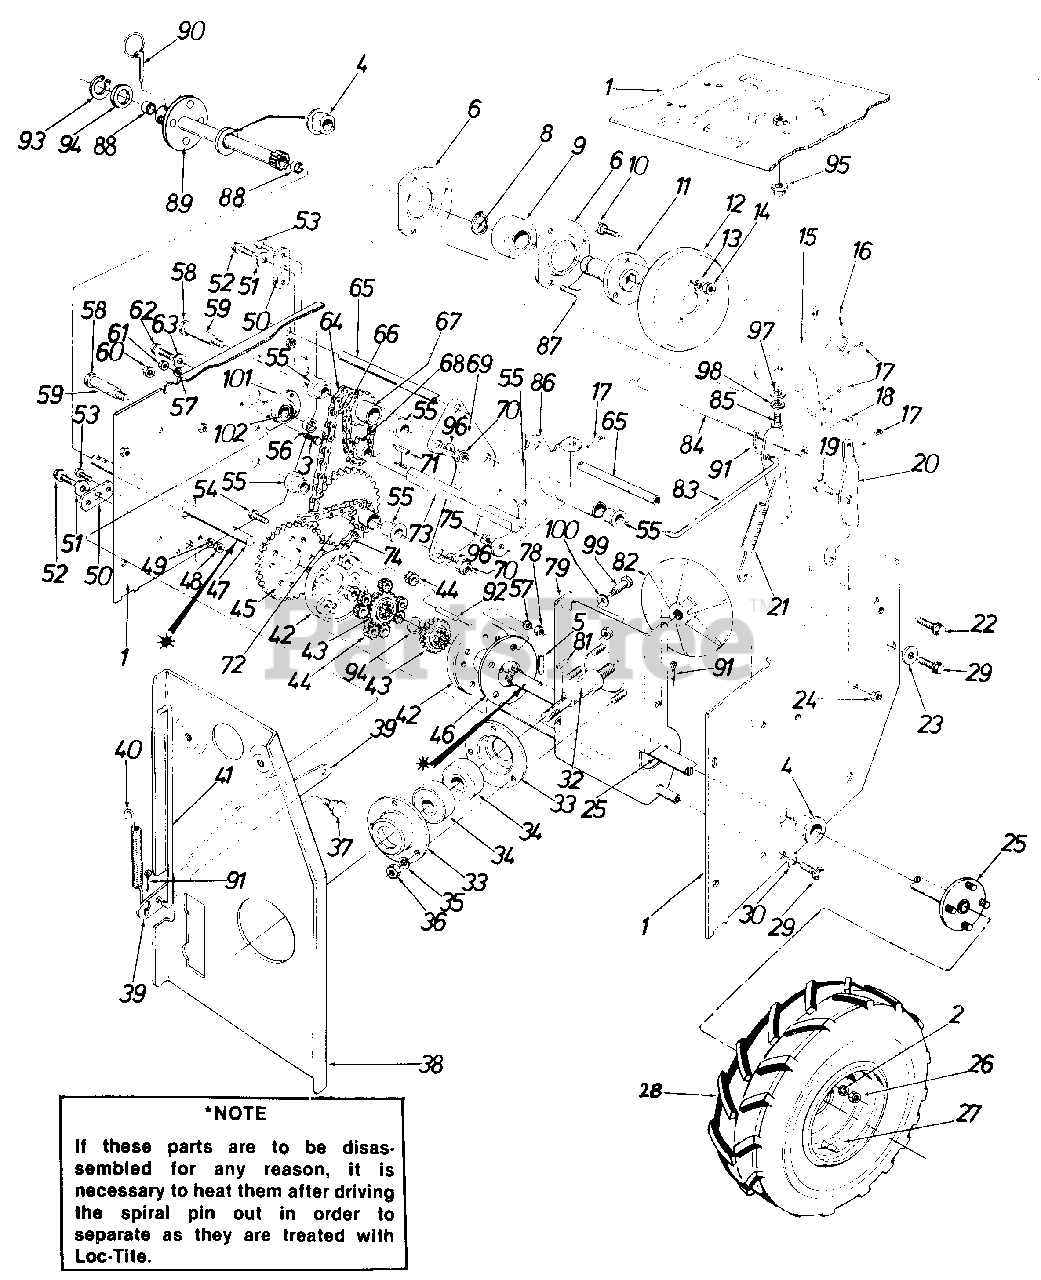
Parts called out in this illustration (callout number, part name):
1	Frame Ass'y.
2	L-Wash. 3/8" Scr.
3	Hex Bolt 1/4-20 x .62" Lg.
4	Flange Brg. w/Flats 1.00" I.D.
5	H-Spring Pin Spiral 3/16" Dia. x 1.25" Lg.
6	Bearing Housing
8	Snap Ring for 1.00" Dia. Shaft
9	Ball Brg. 25 mm x 52 mm x 15 mm Thk.
10	Hex Sems Scr. 5/16-18 x .75" Lg.
11	Friction Wheel Adapter
12	Friction Wheel Ass'y.
13	L-Wash. 5/16" Scr.
14	Hex Nut 5/16-18" Thd.
15	Sliding Linkage Brkt.
16	Brake Rod - .31" Dia. x 2.00" Lg.
17	Cot. Pin 3/32" Dia. x .75" Lg.
18	Shifting Linkage Rod .31" Dia. x 2.25" Lg.
19	Shld. Scr. .625" Dia. x .170" Lg.
20	Shifting Linkage Brkt.
21	Extension Spring .73 O.D. x 4.31" Lg.
22	Hex L-Scr. 5/16-18 x .62" Lg.
23	Fl-Wash. .345 I.D. x .75 O.D. x .060
24	Hex Cent. L-Nut 3/8-16 Thd.
25	Differential Shaft Ass'y. - L.H.
26	Hex Nut 3/8-16 Thd.
27	Wheel Rim Ass'y.
28	Wheel Ass'y. Comp. 16.0 x 4.80-8
29	Hex L-Scr. 5/16-18 x .62" Lg.
30	Fl-Wash. .345" I.D. x .75 O.D. x .060
32	Drive Plate Spindle
33	Bearing Housing
34	Ball Brg. .787 I.D. x 1.85 O.D. x .56
35	L-Wash. 5/16" Scr.
36	Hex Nut 5/16-18 Thd.
37	Shld. Scr. .625" Dia. x .170" Lg.
38	Engine Brkt. Ass'y.
39	Auger Clutch Brkt.
40	Extension Spring .38 O.D. x 3.18" Lg.
41	Auger Clutch Rod .31" Dia. x 10.62" Lg.
42	Differential Housing
43	20 Tooth Spur Gear
44	9 Tooth Spur Gear
45	28 Tooth Sprocket
46	Differential Hsg. Support Plate
47	Differential Connecting Shaft
48	Hex Nut 1/4-20 Thd.
49	L-Wash. 1/4" Scr.
50	Pivot Axle Brkt.
51	Fl-Wash. .345" I.D. x .88" O.D. x .060
52	Hex L-Scr. 5/16-18 x .62" Lg.
53	Hex Scr. 1/4-20 x .62" Lg.
54	Hex Scr. 1/4-28 x 1.75" Lg.
55	Flange Brg. - .630" I.D.
56	Spacer .51" I.D. x .69" O.D. x .44
57	L-Wash. 1/4" Scr.
58	Hex Scr. 3/8-24 x 2.75" Lg.
59	Sprocket Hub Tubing 1.900" Lg.
60	Hex Cent. L-Nut 3/8-16 Thd.
61	Hex Nut 1/4-20 Thd.
62	Hex L-Scr. 5/16-18 x .62" Lg.
63	Bell-Wash. .345" I.D. x .88 O.D. x .060
64	#41 Chain - 1/2" Pitch x 43 Links
65	Sliding Support Axle
66	#41 Chain 1/2" Pitch x 19 Links
67	9 and 14 Teeth Sprocket Hub Ass'y.
68	8 Teeth Sprocket
71	#9 Hi-Pro Key 3/32 x 5/8" Dia.
72	9 and 32 Teeth Sprocket Hub Ass'y.
73	Hex Shaft
74	#420 Chain - 1/2" Pitch x 37 Links
75	Hex Ins. Jam L-Nut 1/4-28"
78	Hex Nut 1/4-28 Thd.
82	Aluminum Drive Plate
83	Drive Clutch Rod .31" Dia. x 7.38" Lg.
84	Drive Clutch Brkt. Ass'y.
85	Hex Scr. 3/8-16 x 1.00" Lg.
86	Sliding Brkt. Ass'y.
87	Hex Scr. 1/4-28 x .62" Lg.
88	Sleeve Brg. .630 I.D.
89	Differential Tubing Ass'y. - R.H.
90	Klick Pin 1/4" Dia. x 1.75" Lg.
91	Internal Cot. Pin 5/16 Dia.
92	Differential Pin
93	Snap Ring .625 Shaft
94	Fl-Wash. .62 I.D. x 1.25 O.D. x .060
95	Shld. Spacer 5/8" I.D.
96	L-Wash. 3/8" Scr.
97	Fl-Wash.
98	L-Wash. 3/8" Scr.
99	Shld. Scr.
100	Bell-Wash.
101	Bearing Housing
102	Ball Bearing
